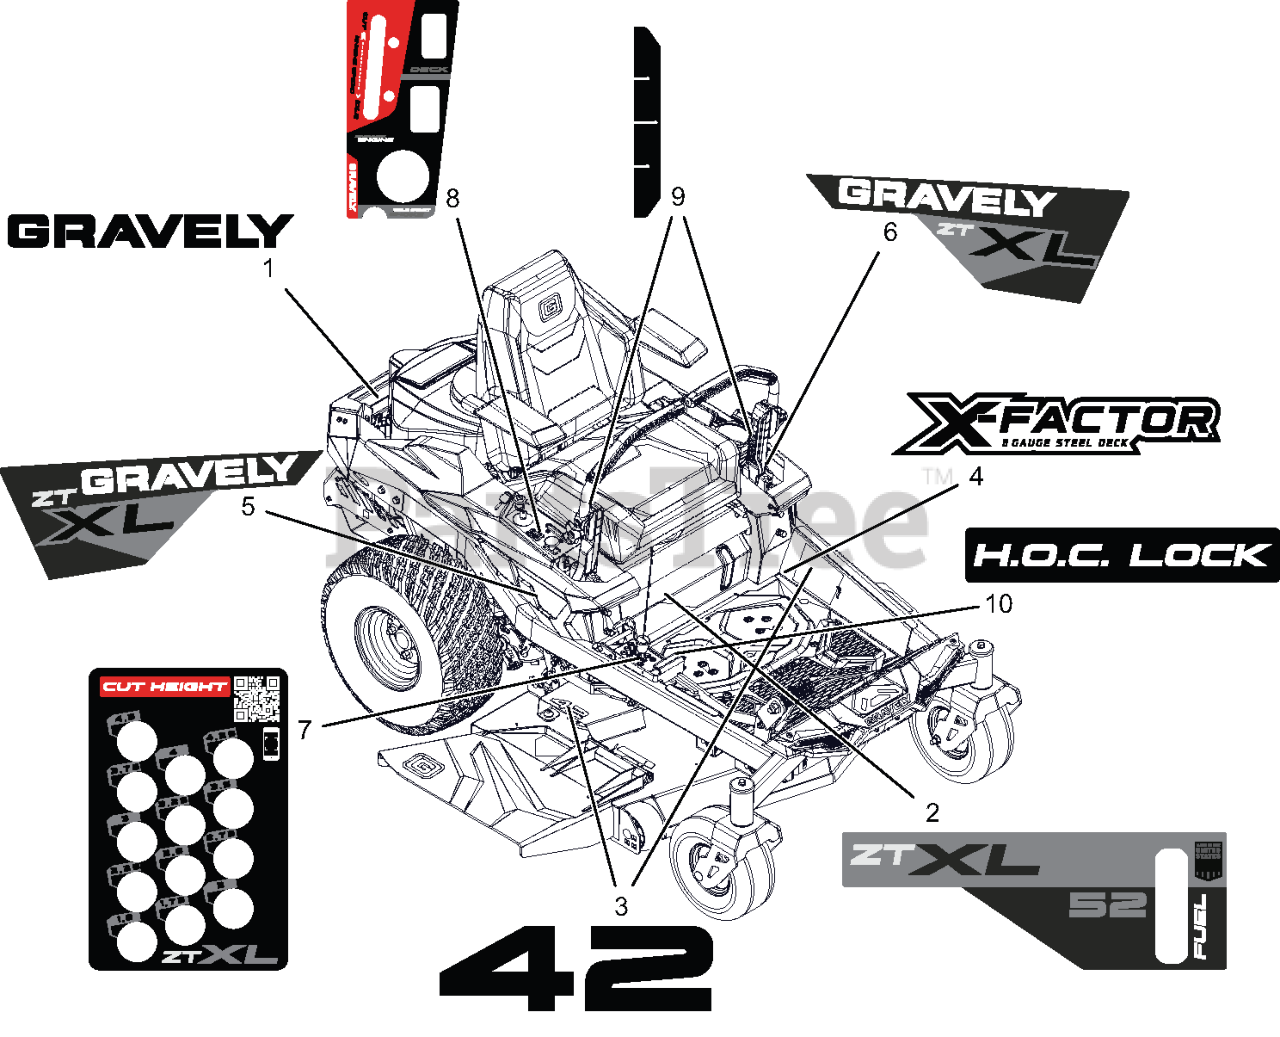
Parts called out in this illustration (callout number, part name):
1	DECAL- GRAVELY
2	DECAL- ZTXL 42-KICK PLATE
3	DECAL- DECK 42"
4	DECAL- DECK X-FACTOR
5	DECAL- ZT XL FENDER RH
6	DECAL- ZT XL FENDER LH
7	DECAL- HEIGHT OF CUT-XL
8	DECAL- CONTROL PANEL-GRAVELY
9	DECAL- HIRTH INDICATOR
10	DECAL- HOC LOCK
